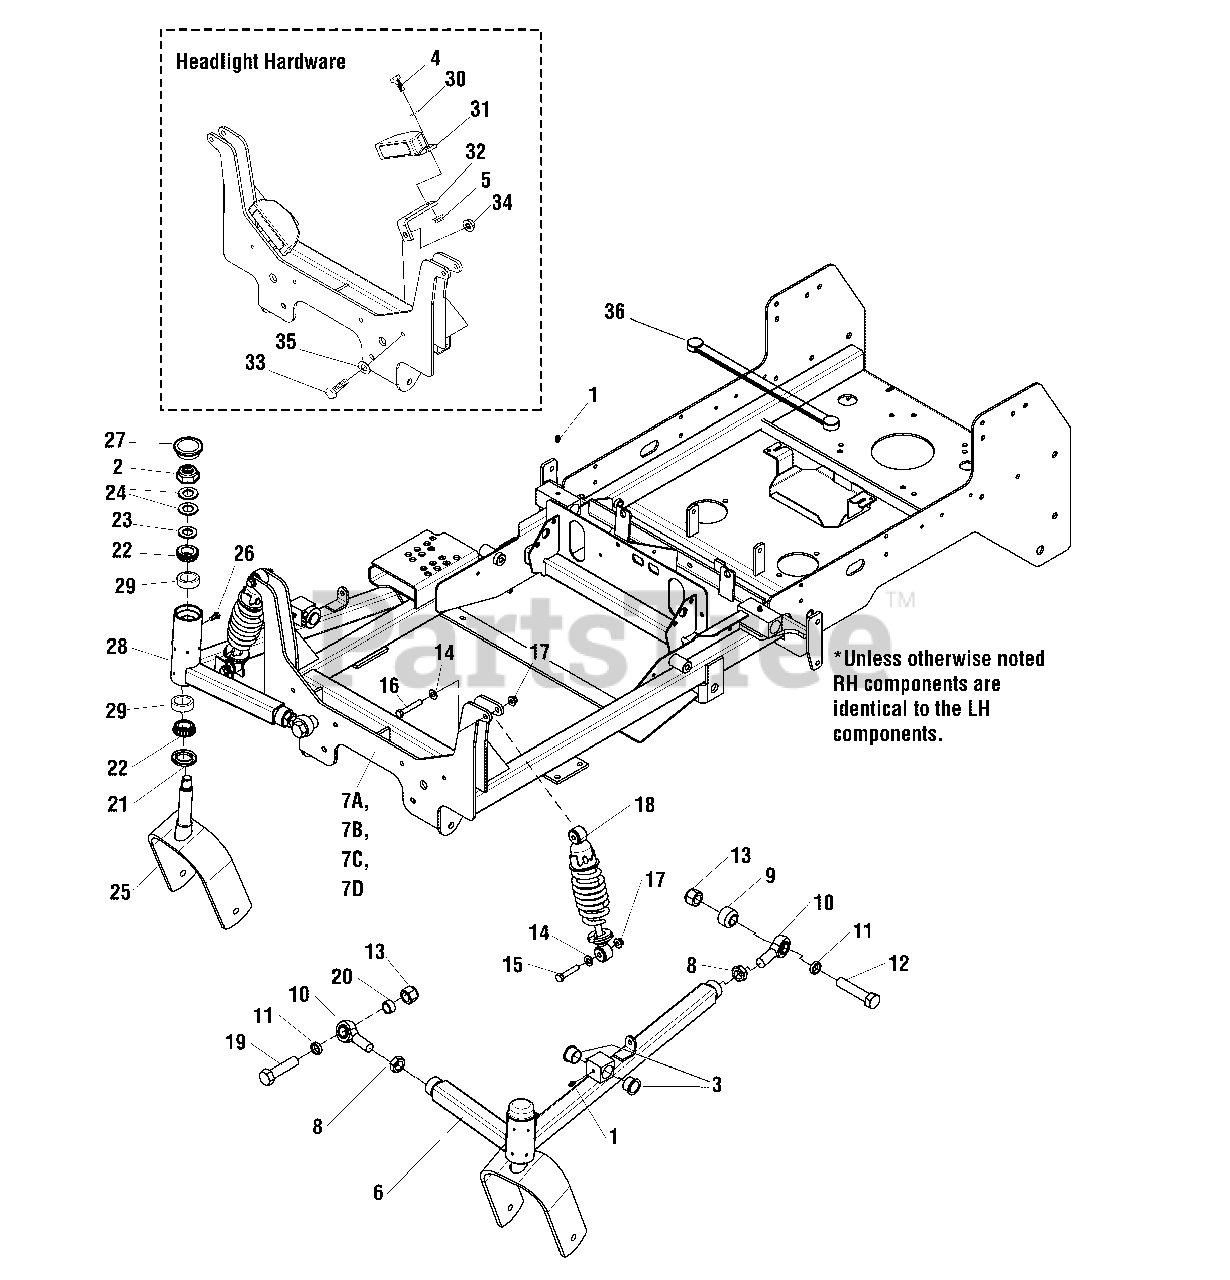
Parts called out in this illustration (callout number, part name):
1	GREASE FITTING, 1/4-28 STR
2	NUT, 3/4-16 HEX JAM NYLON LOCK
3	BUSHING, 1.00 X 1.13 X .75, PLASTIC
4	BOLT, 1/4-20 X 1", GD
5	NUT, 1/4-20 HEX NYLOCK FLANGE (5025391)
6	WELD, FRONT A-ARM, LH - ORANGE
8	NUT, HEX JAM, 3/4-16
9	SPACER, .75 X 1.50 X 1.00
10	BALL JOINT, 3/4-16 MALE
11	SPACER, .76 X 1.00 X .25
12	3/4-16 X 3.5" HHCS YZP GR 5
13	NUT, 3/4-16 HEX NYLON LOCK
14	WASHER, 3/8 GD.9 FLAT
15	BOLT, 3/8-16 X 2" GD5
16	BOLT, 3/8-16 X 2-1/4" GD5
17	NUT, 3/8-16 HEX NYLOCK FLANGE
18	COIL - OVER SHOCK ASSEMBLY
19	BOLT, 3/4-16 X 3" GD 5
20	SPACER, .76 X 1.00 X .50
21	SEAL, GREASE
22	BEARING, TAPPERD ROLLER, 1"
23	WASHER, 3/4" SAE
24	WASHER, BELLEVILLE - 1.500 X .755
25	WELD, CASTER YOKE - ORG
26	BOLT, 1/4-28 X 1/2, GD5 YZ
27	CAP, LOW PROFILE, STEEL
28	WELD, FRONT A-ARM, RH - ORANGE
29	BEARING CUP
30	WASHER, 1/4 SAE (5025154)
31	HEADLIGHT, 4" RECTANGULAR
32	MOUNT, HEAD LIGHT - ORANGE
33	BOLT, 5/16-18 X 1"
34	NUT, 5/16-18" NYLOCK FLANGE
35	WASHER, 5/16" SAE FLAT
36	STRAP-BLACK RUBB
